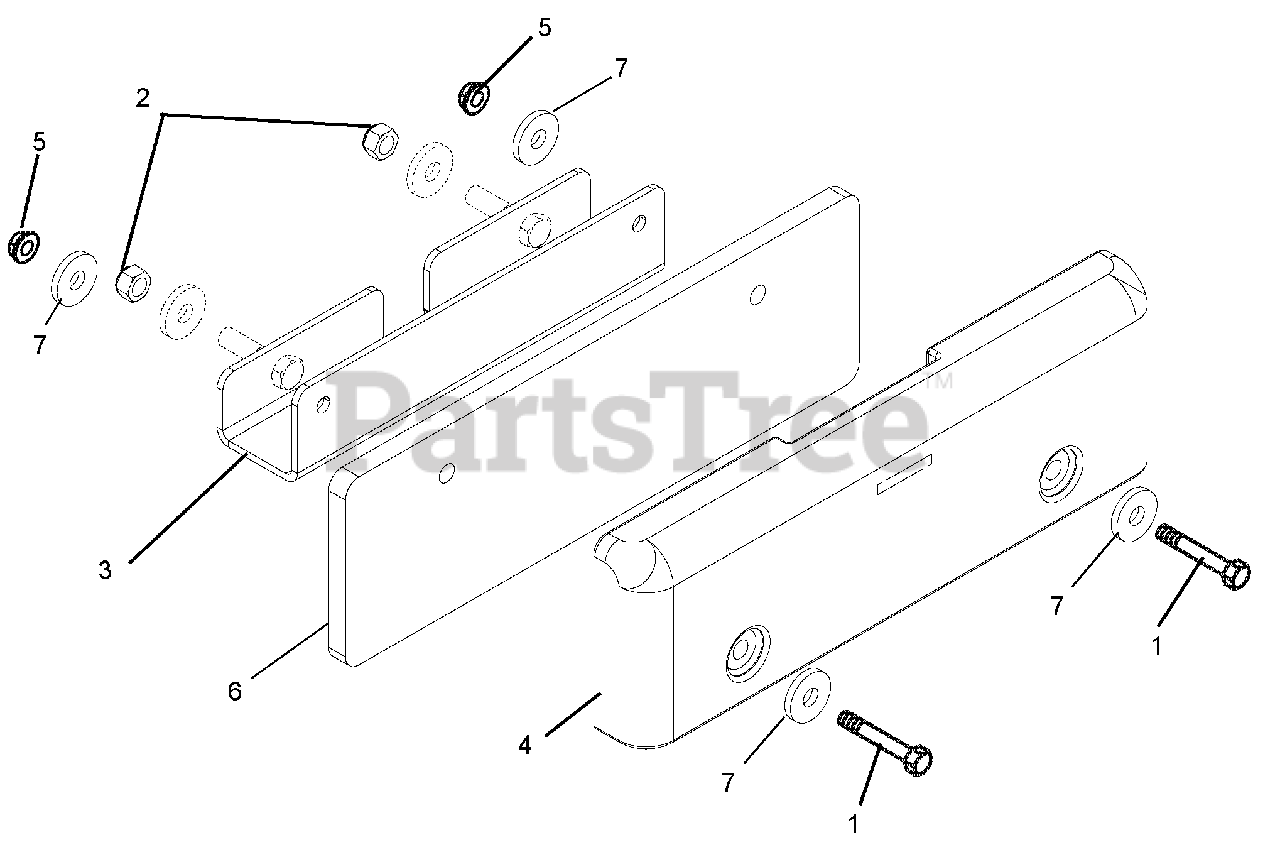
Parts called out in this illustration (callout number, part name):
1	Bolt, Hex .50-13 x 3.50 Grade 5
2	Nut, Nyloc Flange .62-11
3	Bracket, Bagger Weight
4	Counterweight
5	Nut, .50-13 Nyloc Flange
6	Counterweight
7	Washer, Flat-Steel .50 x 1.25 x .083
